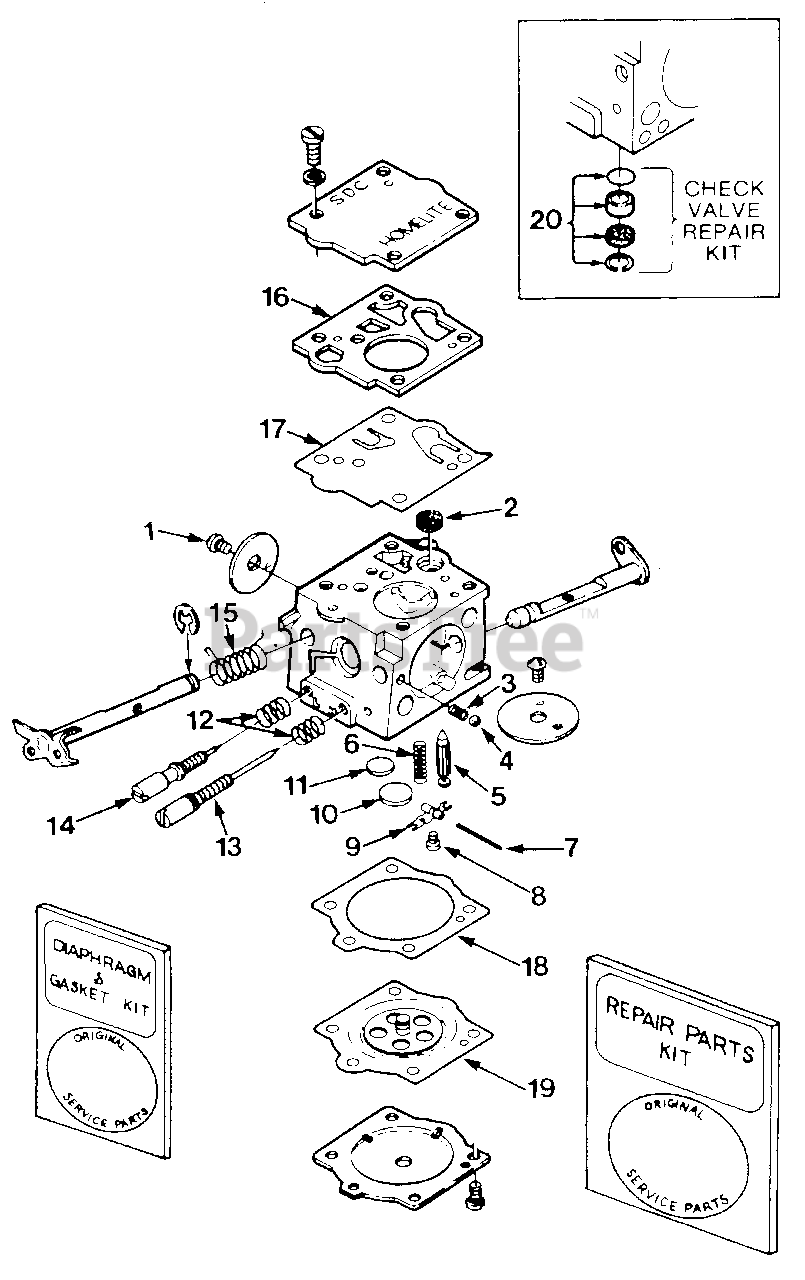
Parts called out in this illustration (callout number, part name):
1	Repair Kit
2	Repair Kit
3	Repair Kit
4	Repair Kit
5	Repair Kit
6	Repair Kit
7	Repair Kit
8	Repair Kit
9	Repair Kit
10	Repair Kit
11	Repair Kit
12	Repair Kit
13	Repair Kit
14	Repair Kit
15	Repair Kit
16	Repair Kit
17	Repair Kit
18	Repair Kit
19	Repair Kit
20	Check Valve Kit
